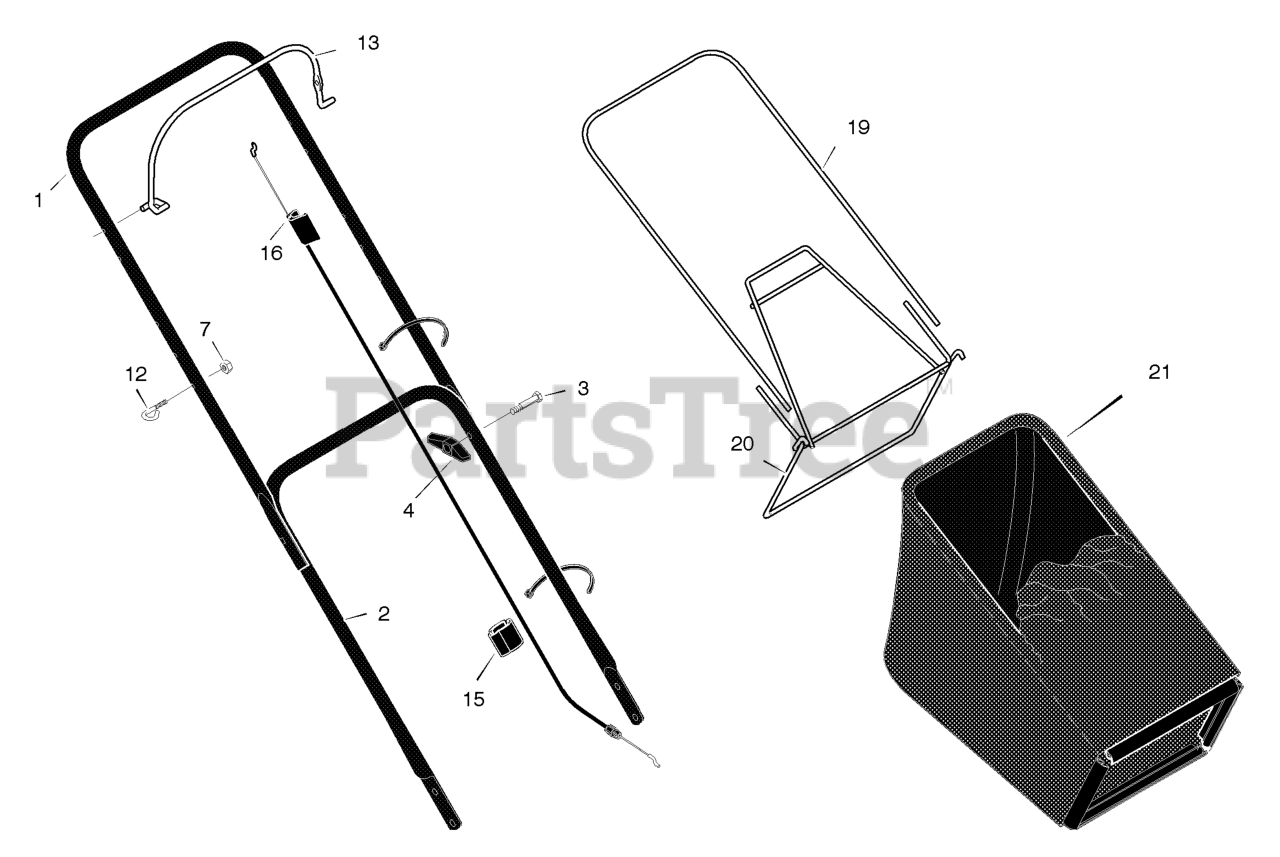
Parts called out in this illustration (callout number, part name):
1	Handle, Upper (Black)
2	Handle, Lower (Black)
4	Knob, Plastic
7	Locknut
12	Guide, Rope
13	Engine Stop Lever
15	Fastener, Cable
16	Engine Stop Cable
19	Frame, Top
20	Frame Assembly
21	Bag, Cloth - Black
